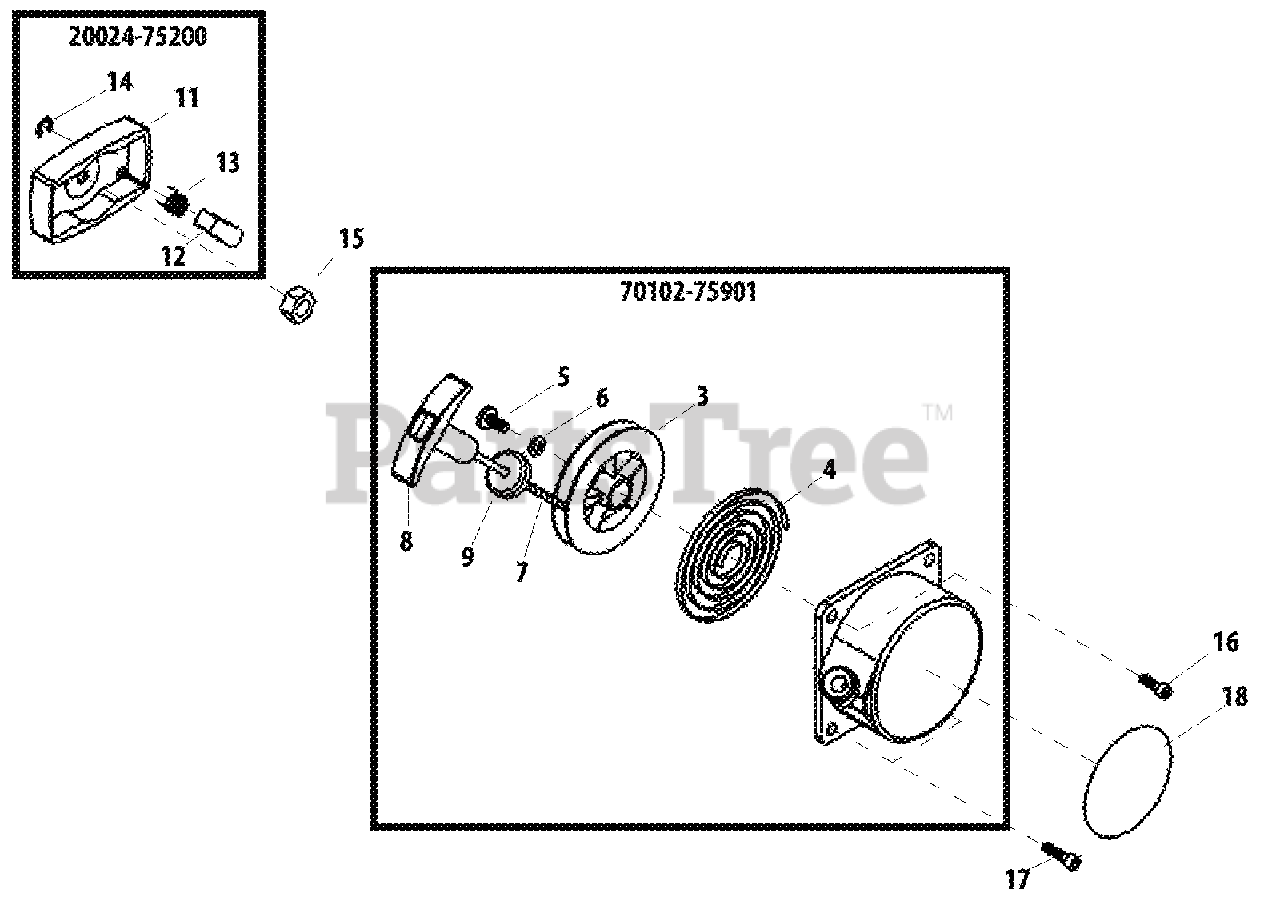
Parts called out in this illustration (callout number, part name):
3	REEL, ROPE
4	SPRING
5	SCREW
6	WASHER
7	ROPE
8	GRIP, STARTER
9	GUIDE, ROPE
11	CASE, PAWL
12	PAWL, STARTER
13	SPRING, RETURN
14	RING, RETAINING
15	NUT
16	SCREW - 5X16
17	SCREW - 5X25
18	LABEL
2002475200	STARTER PAWL ASSY
7010275901	STARTER ASSY
